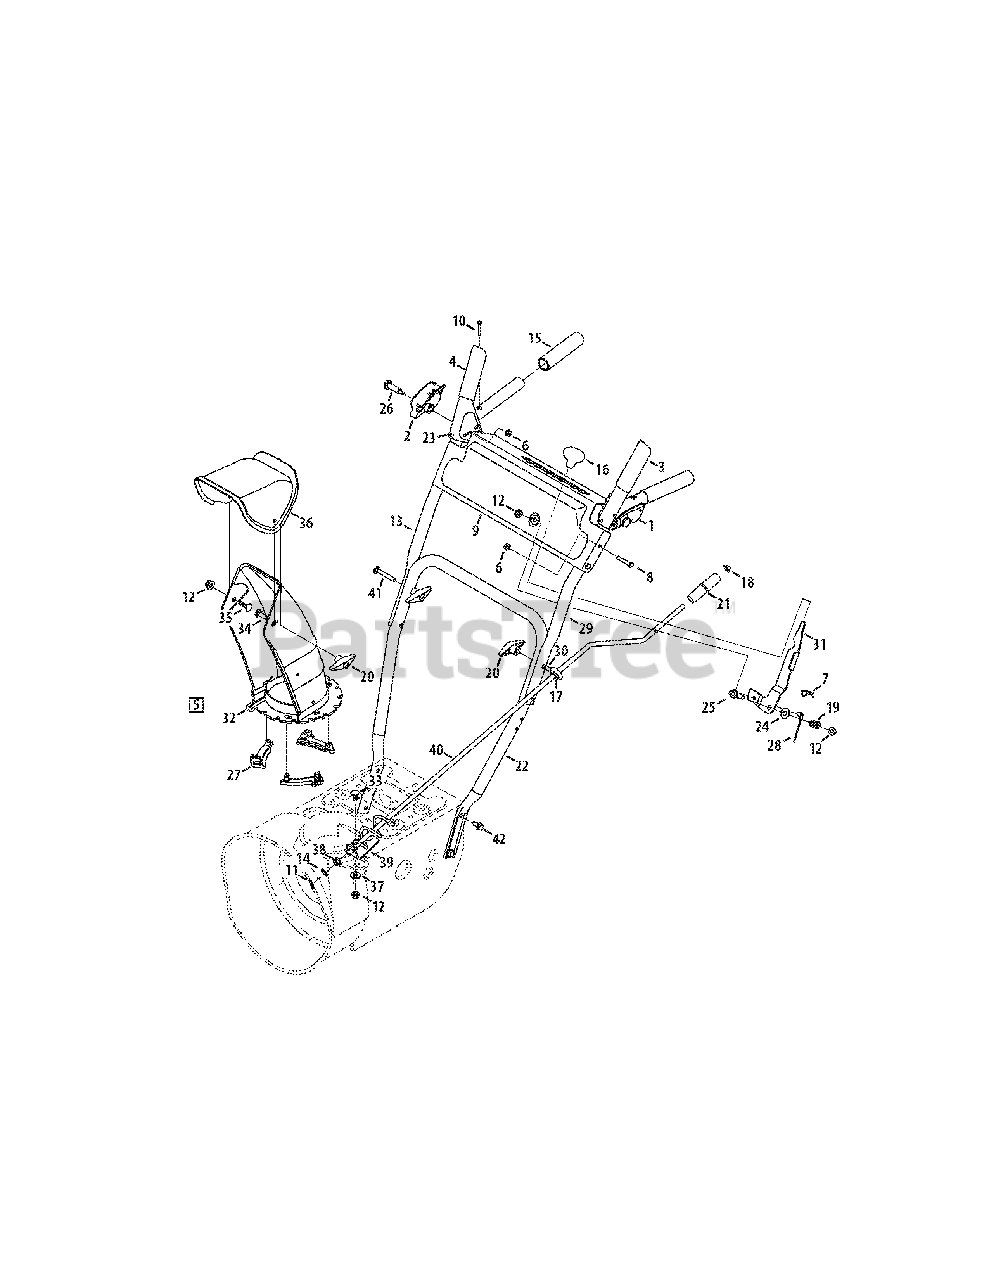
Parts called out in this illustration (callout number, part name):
1	Handle Assembly, Clutch Lock, LH
2	Handle Assembly, Clutch Lock, RH
3	Handle Ass’y, Engage, LH
4	Handle Ass’y, Engage, RH
5	Chute, Lwr (Incl. Ref. # 27, Qty. 3)
6	Nut, Flange Lock, 1/4-20
7	Click Pin
8	Screw, 1/4-20 x 1.50
9	Panel, Handle, (no cutout)
10	Screw, Machine, #10-24, 1.375
11	Pin, Cotter, .072 x 1.13
12	Nut, Flange Lock, 5/16-18, Nylon
13	Handle, Upper, RH
14	Washer, Flat, .375 x .738 x .063
15	Grip, 1.0 ID x 5.0
16	Knob, Shift, Black
17	Grommet, .44 ID x .94 OD x .50
18	Cap, Push, 3/8 Rod
19	Spring, .39 x .60 x .88
20	Knob, 5/16-18, Black
21	Crank Knob, 1.0 Dia. x 3.2, Black
22	Handle, Lower
23	Bumper, Rubber, .62 OD x .22
24	Washer, Flat, .385 x .870 x .092
25	Bolt, Shoulder, 5/16-18 x 0.905
26	Screw, Shoulder, .43 x 1.3, 1/4-20
27	Chute, Flange Keeper
28	Cable, Speed Selector
29	Handle, Upper, LH
30	Eye Bolt, Chute Crank
31	Shift Lever
32	Chute, Lower, 5.0 Dia.
33	Bolt, Carriage, 5/16-18, 1.0
34	Bolt, Carriage, 5/16-18, 1.0
35	Bolt, Carriage, 5/16-18, .750
36	Chute, Upper, w/ Label
37	Washer, .349 x .879 x .063
38	Bushing, Plastic, .380
39	Bracket, Chute Crank
40	Crank Assembly, Chute
41	Screw, Carriage, 5/16-18, 2.25
42	Screw, 5/16-18, 2.25, Gr5
